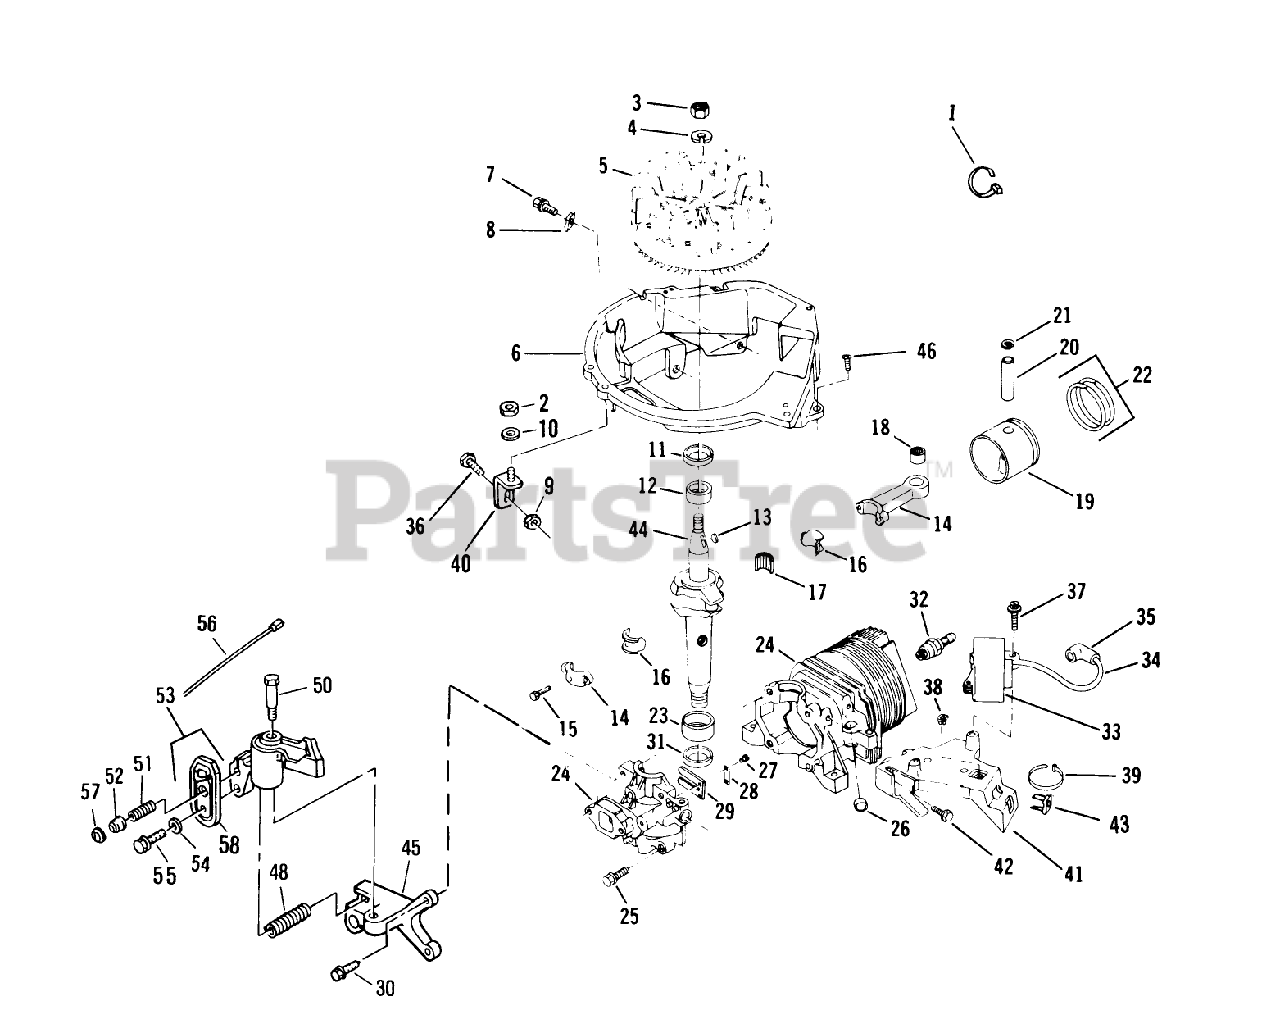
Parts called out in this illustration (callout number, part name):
2	LOCKNUT E
3	NUT
5	FLYWHEEL ASSY F
6	BASE SHROUD F
7	SCREW-SEMS
9	NUT-LOCK F
10	WASHER S
11	SEAL-OIL
12	BEARING V
13	KEY
15	SCREW-HSH
16	LINER ASM
17	BEARING-NEEDLE
18	BEARING AY F
21	RING-RETAINING
23	BEARING V
25	SCREW S
26	PLUG-CORE VF
27	SCREW-HH
28	PLATE-BACKUP, REED
31	SEAL-OIL
34	HT LEAD&COVER XEV
36	BOLT F
38	NUT-CLIP
40	BRACE AY F
41	BRACKET S
43	NUT-CLIP
45	BRACKET-BRAKE F
46	SCREW F
48	SPRING-BRAKE
51	SPRING
52	ACTUATOR-LEVER, BRAKE
54	WASHER
56	WIRE LEAD AY F
57	RETAINER S
